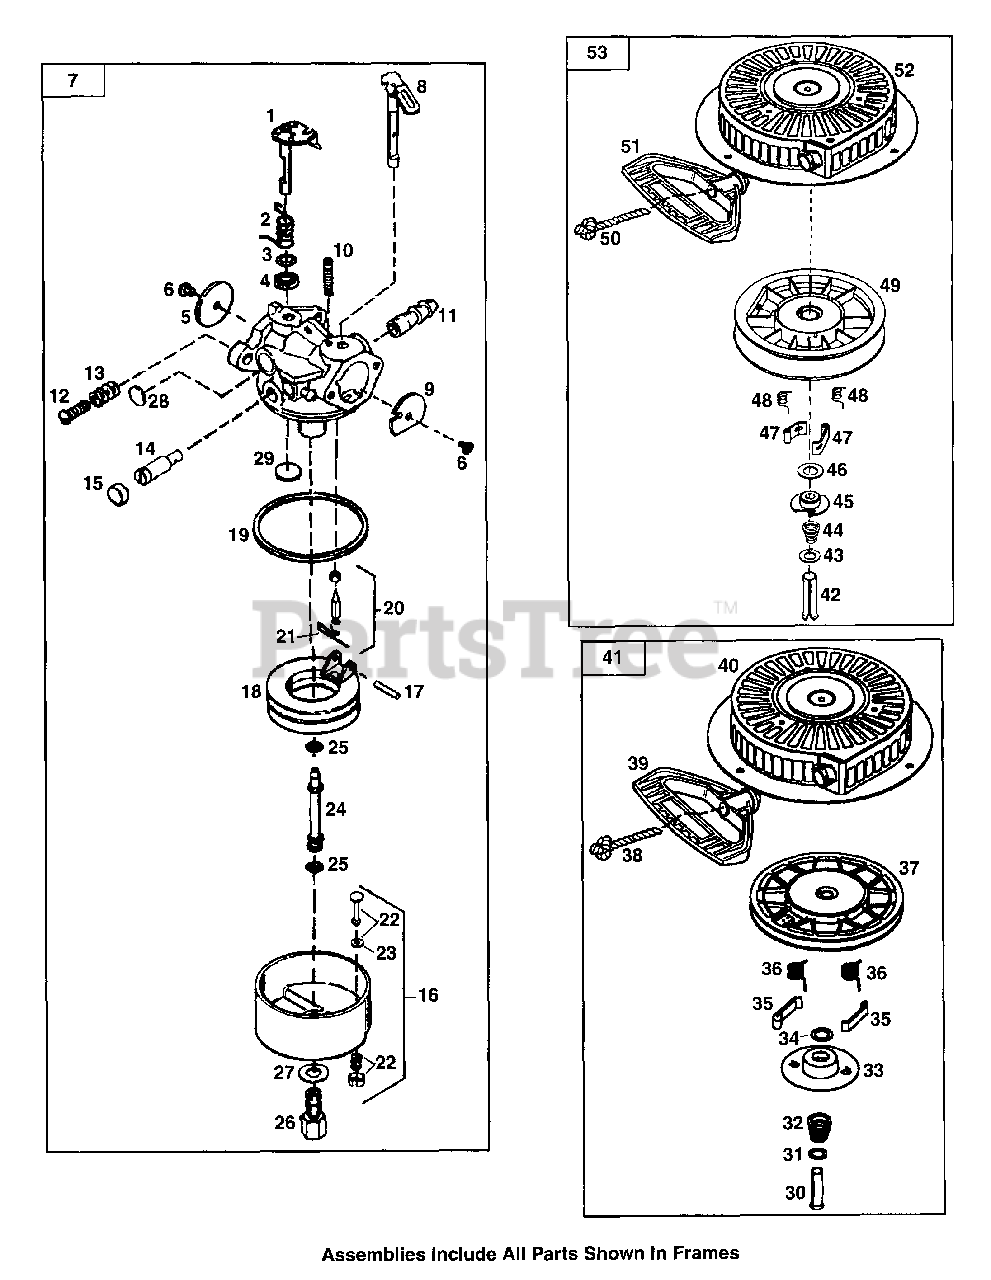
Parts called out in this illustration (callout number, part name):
1	Throttle Shaft & Lever Ass'y
2	Throttle Return Spring
3	Dust Seal Washer
4	Dust Seal (Throttle)
5	Throttle Shutter
6	Shutter Screw
7	Carburetor Ass'y
8	Choke Shaft & Lever Ass'y
9	Choke Shutter
10	Choke Positioning Spring
11	Fuel Fitting
12	Throttle Crack/Idle Speed Screw
13	Tension Spring
14	Idle Restrictor Screw
15	Idle Restrictor Screw Cap
16	Float Bowl
17	Float Shaft
18	Float
19	Float Bowl "O" Ring
20	Inlet Needle, Seat & Clip
21	Spring Clip
22	Bowl Drain Ass'y
23	Drain Plunger Gasket
24	Main Nozzle Tube
25	Main Nozzle Tube "O" Ring
26	High Speed Bowl Nut
27	Bowl Nut Washer
28	Welch Plug, Idle Mixture Well
29	Welch Plug, Atmospheric Vent
30	Spring Pin,
32	Brake Spring
35	Starter Dog
36	Dog Spring
37	Pulley & Rewind Spring Ass'y
38	Starter Rope (98")
39	Mitten Grip Starter Handle
40	Starter Housing Ass'y
41	Rewind Starter Ass'y
42	Spring Pin
44	Brake Spring
47	Starter Dog
48	Dog Spring
49	Pulley & Rewind Spring Ass'y
50	Starter Rope (98")
51	Mitten Grip Starter Handle
52	Starter Housing Ass'y
53	Rewind Starter Ass'y
